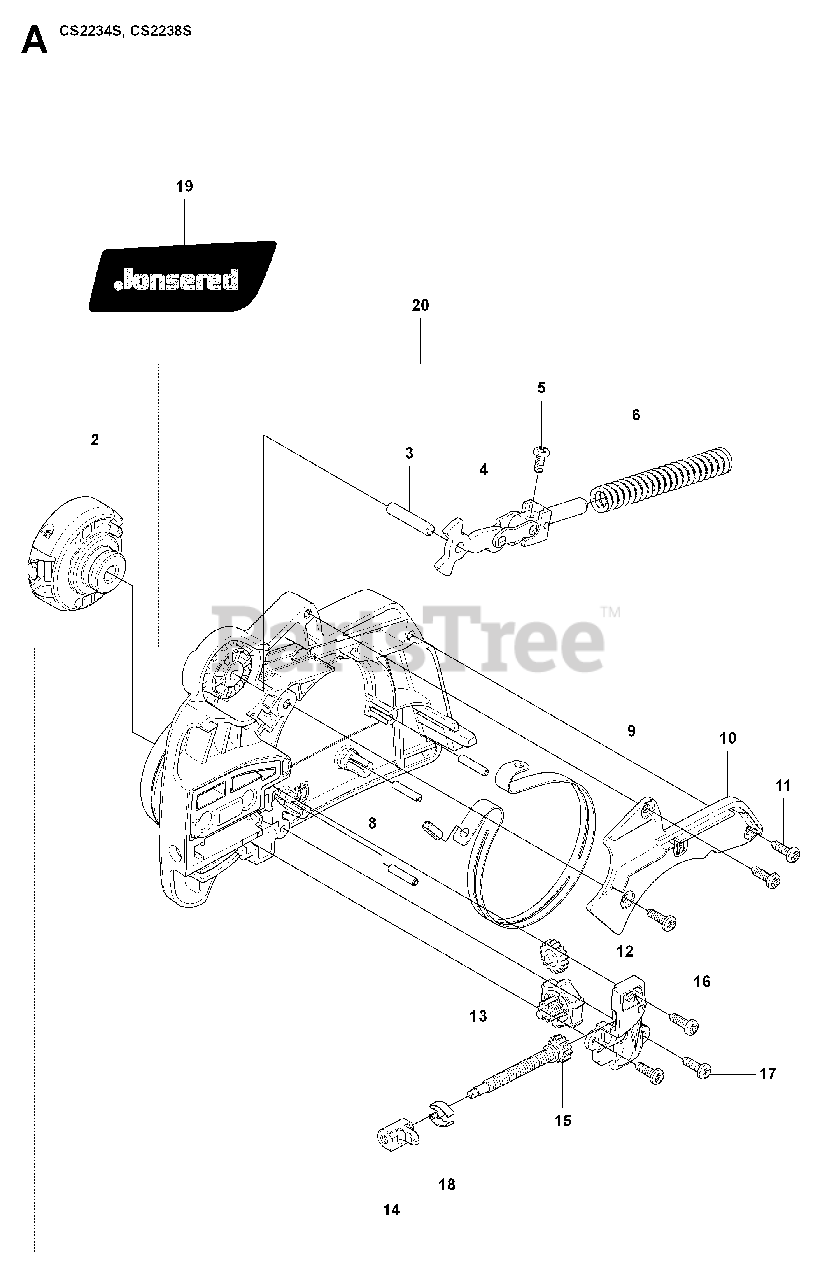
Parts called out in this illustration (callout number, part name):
2	KNOB
3	PIN
4	FRONT LINK ASSY
5	SCREW
6	SPRING
8	PIN
9	BRAKE BAND
11	SCREW
12	GEAR IDLER
13	%WHEEL GEAR ADJUSTMENT
14	PIN BAR ADJUSTING
15	SCREW
17	SCREW
18	CLIP
20	CHAIN BRAKE ASSY
